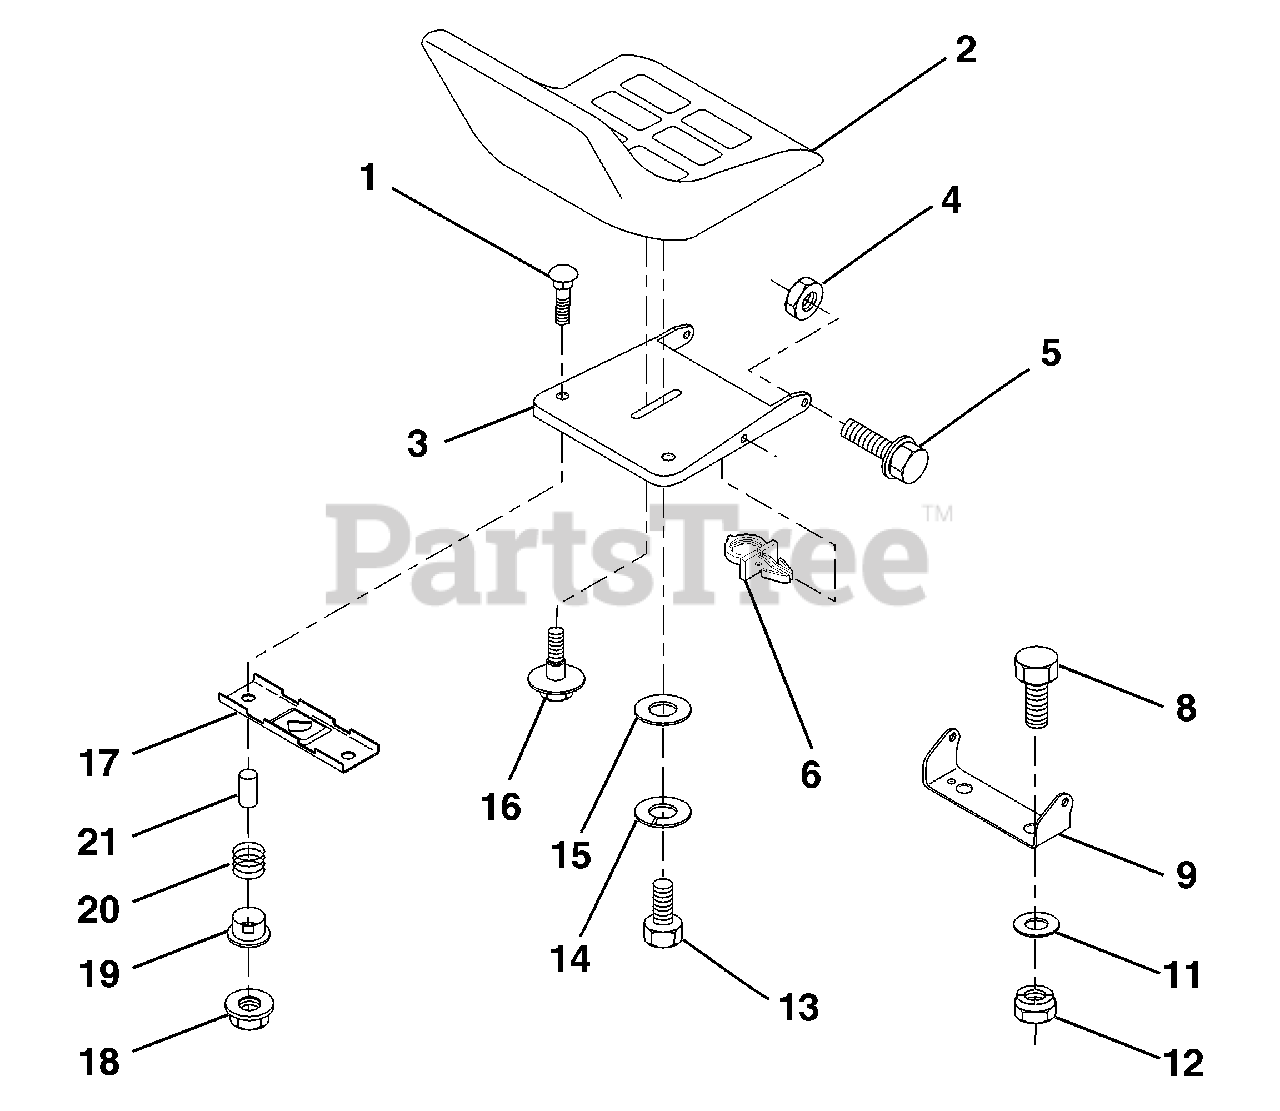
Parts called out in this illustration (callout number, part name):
1	Bolt, Carriage 1/4-20 x 1-1/2
2	Seat
3	Pan, Seat
4	Locknut, Hex w/Ins 5/16-18
5	Bolt, Shoulder 5/16-18 UNC
6	Clip, Push-in
8	Bolt, Fin Hex 3/8-16 UNC x 1
9	Bracket, Pivot Seat
11	Washer 12/32 x 2 x 10 Ga.
12	Nut, Lock Hex w/Wsh 3/8-16
13	Bolt Hex 1/2-13 x 7/8
14	Washer Lock Hvy. Hlicl Spring 1/2
15	Washer, 17/32 x 1-3/16 x 12 Ga.
16	Bolt, Shoulder
17	Bracket, Switch, Mounting
18	Nut, Hex Large Flange Lock
19	Bushing, Snap
20	Spring, Compression
21	Spacer, Split 28 Id. x .88 Lg.
